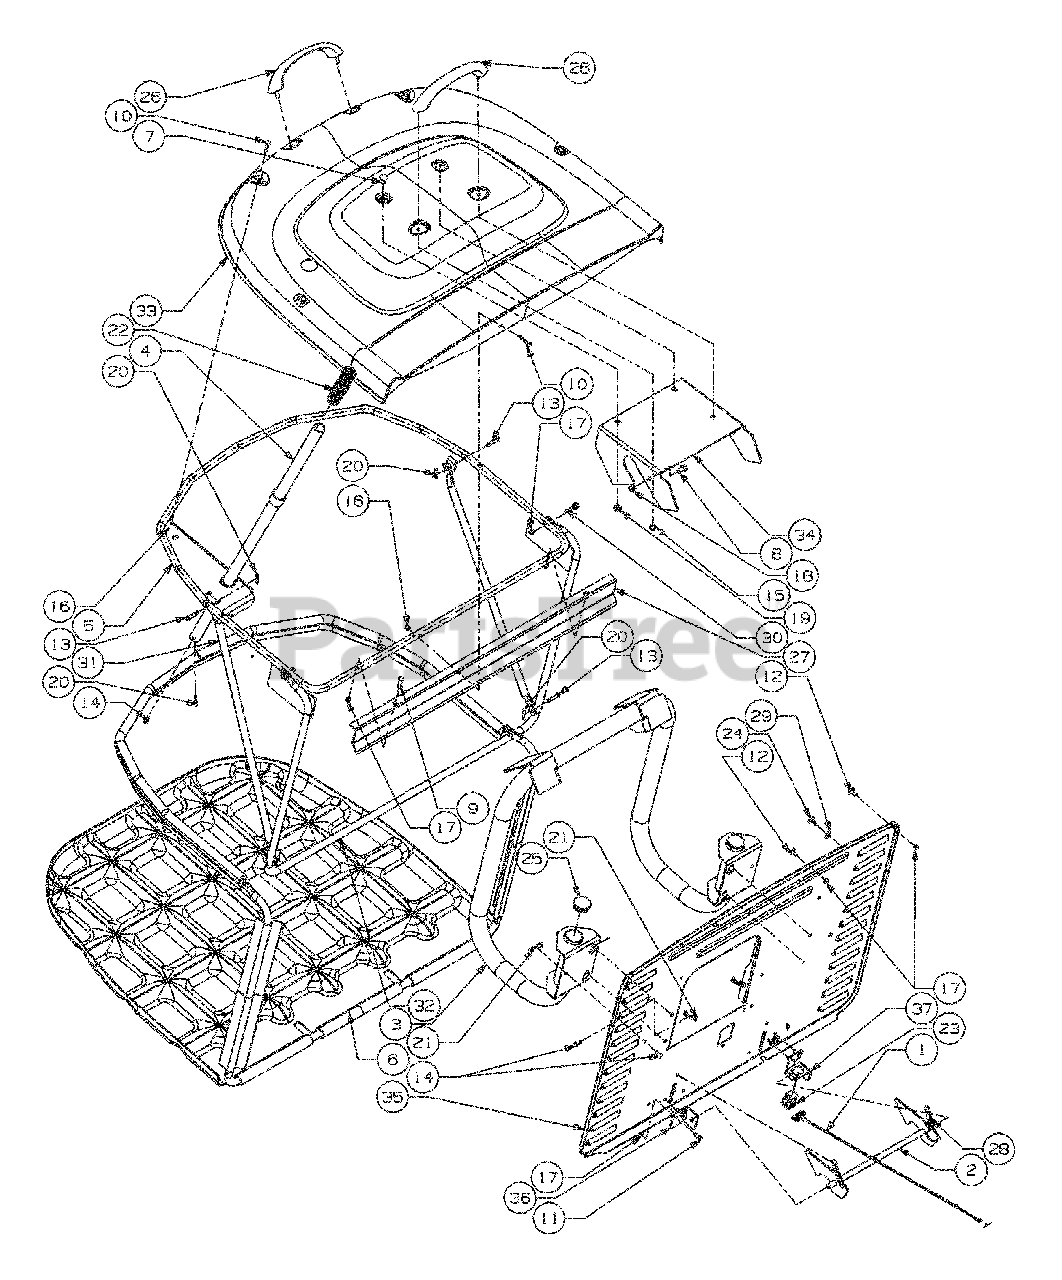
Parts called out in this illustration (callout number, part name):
6	GRSBAG ASM:RR DIS:300L 500S
7	BOLT:CRG:5/16-18:.62:GR1
8	HHCS:M8-1.25:16.00:GR8.8:STD
9	HHCS:M6-1X25:DIN 933 8.8
10	BOLT:CRG:5MM X 30.0 LG
11	SCR:M6-1:16.00 LG DIN 933
12	SCR:TORX:M6-1 X 15.00
13	PIN:CLV:.25 DIA X 1.25 LG
14	PIN:CLV:.25X.50
15	NUT:HEX:1/4-20:SEMS
16	NUT:FLGLK:M5-0.8
17	NUT:HEXLK:M6-1:NYLON DIN 985
18	NUT:HEXLK:M8-1.25:NYLON DIN985
19	NUT:FLGLK:5/16-18:GR5:SD LK
20	PIN:COT:.072 DIA. X 1.13 LG
21	PIN:CLICK:.092 X 1.64 LG
22	GRIP: 1.0 ID X 4.7 LG
23	SW:MT:SNAP NO
24	CLIP:RTCHT:.250 DIA
25	CAP:TUBE:SUPT 300L/250L BAG
26	HNDL:BAG:W/SCR 400/500 S
27	EXTRS:SEAL:BAG 250L/300L
28	EXTENSION SPRING
29	WASH:FLAT .25 X.630 X.0515
33	CVR:BAG:HT:300L
